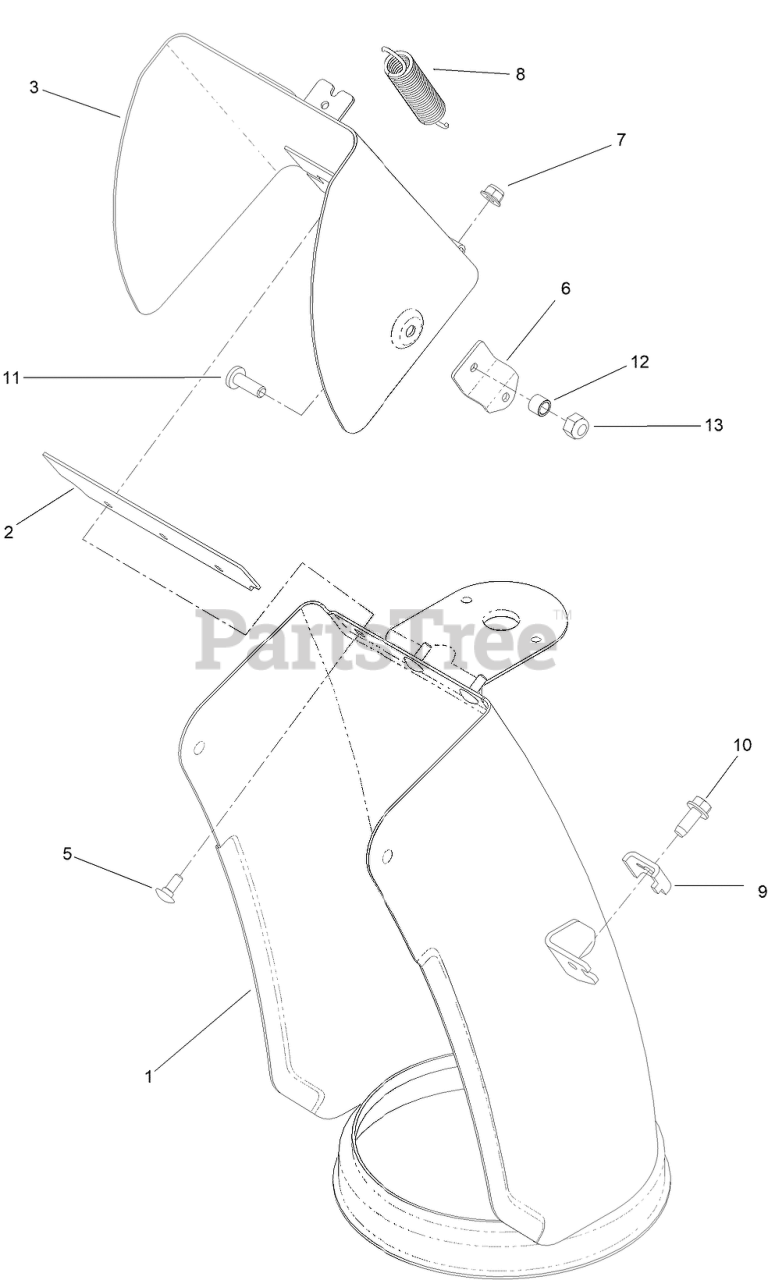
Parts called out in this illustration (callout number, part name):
1	CHUTE-LOWER ASM [RED]
2	GASKET-DEFLECTOR
3	DEFLECTOR WELD ASM
5	BOLT-CARR
6	BRACKET-SPRING
7	NUT-HF
8	SPRING-CHUTE, UPPER
9	CLAMP-CABLE
10	SCREW-HWH
11	SCREW-PH
12	SPACER
13	NUT-HEX
